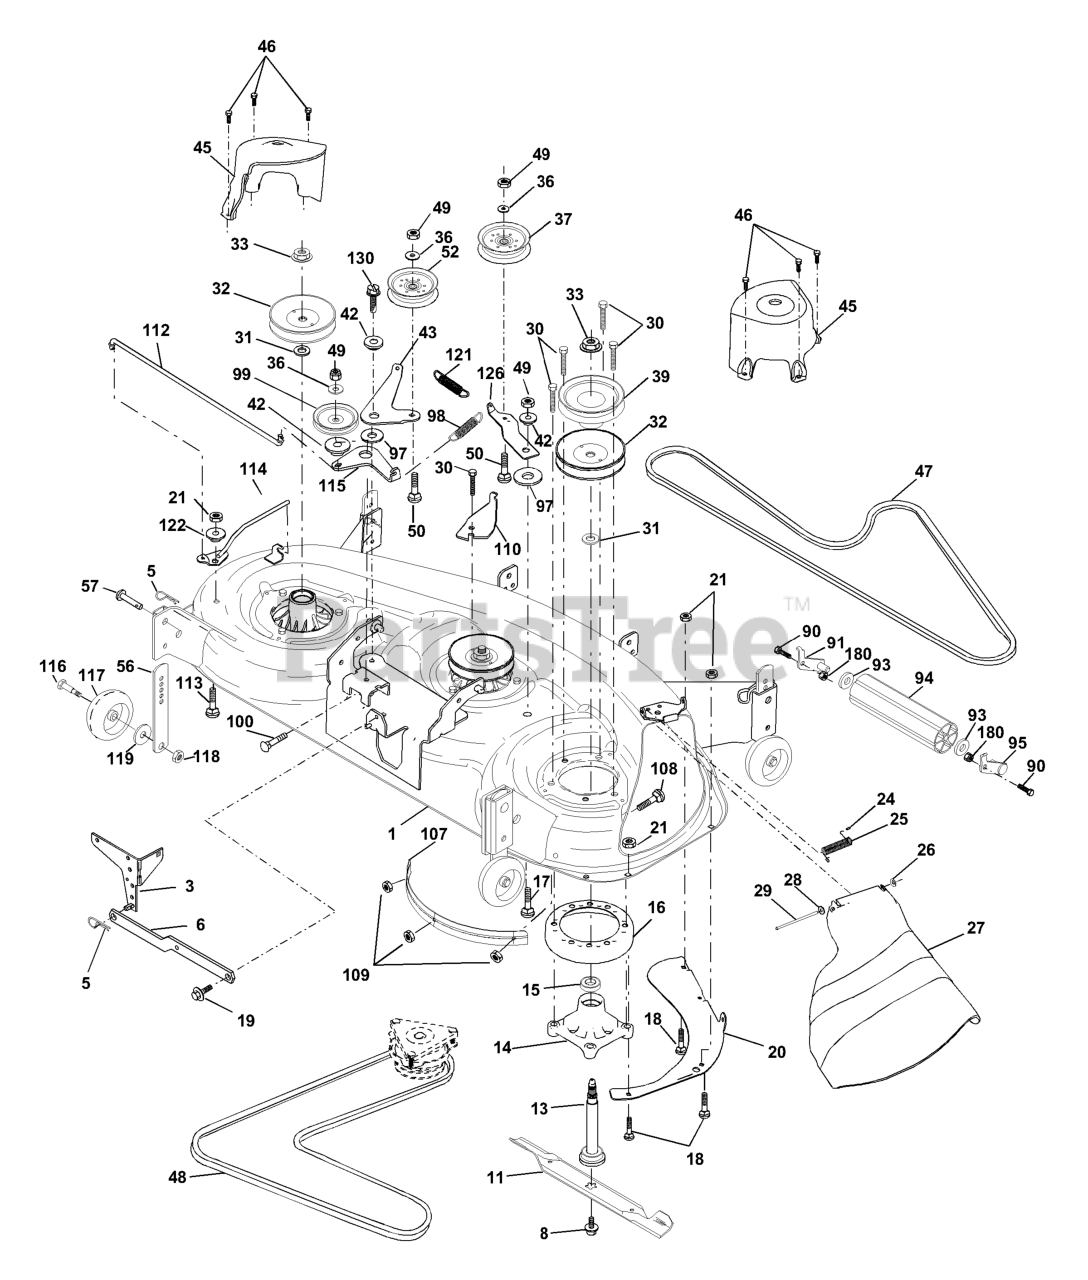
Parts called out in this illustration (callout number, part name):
1	DECK, WELDMENT MWR 48"
3	BRKT ASM SWAY BAR
5	RETAINER-SPRNG RB
6	REAR SUSP ARM
8	BOLT 7/16 ASM BLADE
11	BLADE
13	SHAFT ASM W/LOWER BEARING
14	HOUSING, MANDREL 48"
16	STRIPPER.MANDREL.ROUND.BLACK
17	BOLT
18	BOLT
19	BOLT SHD 5/16-18
20	BAFFLE, VORTEX MWR
21	LOCKNUT
24	CAP-SLEEVE LT
25	SPRING, TORSION
26	NUT PUSH M
27	SHIELD, DEFL. MWR
28	Washer 11/32 x 5/8 x 16 Ga.
29	ROD.HINGE
30	SCREW THDROL ROLLING WASHER HD
31	WASHER
32	PULLEY, MANDREL
33	NUT, FLG TOPLOCK 9/16"
36	WASHER
37	PULLEY.IDLER.FLAT.PLATED
39	PULLEY.DRIVEN.DECK.48'
42	SPACER RETAINER
43	ARM, IDLER SECONDARY
45	COVER, MANDREL DECK
46	SCREW.1/4-20X5/8
47	V-BELT, MWR SECONDARY
48	V-BELT PRIMARY 48"
50	BOLT.3/8-16X1.50
52	PULLEY.IDLER.FLAT.46.PR.DR.
56	BAR-WHEEL GAUGE
57	RIVET.PIN.HEAD.YELLOW.
90	BOLT RB
91	BRKT ASM NOSEROLLER(L)48"
93	Washer 17/32 x 7/8 x 16
94	NOSE ROLLER 48"
95	BRKT, ASM NOSEROLLER(R)48
97	HARDENED WASHER
98	SPRING, PR. DRIVE
99	PULLEY,IDLER"V"
100	BOLT
107	BAFFLE.VAC.EDGE.MOWER.48"
109	NUT.CROWNLOCK.1/4
110	ARM, SPRING SECONDARY
112	LEVER, TENSION RELIEF LINK
113	BOLT CRT
114	LEVER ASM, TENSION RELIEF
115	ARM, SPRING TENSION RELIEF
116	BOLT, SHOULDER
117	WHEEL GAGE DONUT
118	LOCKNUT
119	WASHER.5/16.FLAT.STE.STD.
121	SPRING.DRIVE.SECONDARY.48".DEC
122	BUSHING, PIVOT TENSION RELIEF
126	ARM, IDLER PRIMARY DECK
130	SCREW THDROL 3/8-16 X 1-1/2
180	NUT.71038.31-18.HEX.NYLOCK
